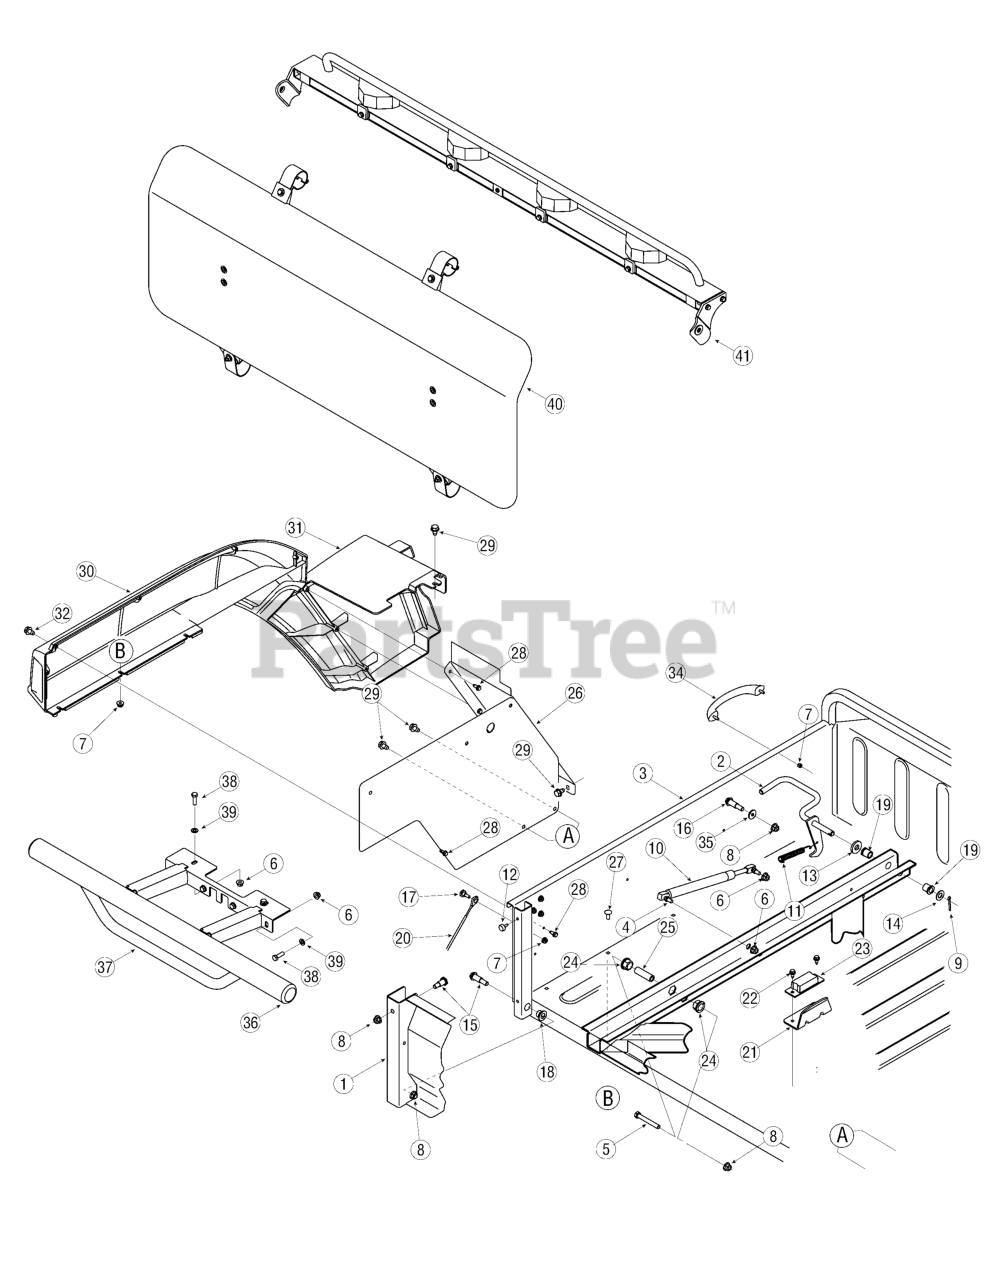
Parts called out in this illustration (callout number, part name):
2	Lvr Asm, bed, latch
4	Stud, ball, 5/16-18
5	Screw, 3/8-16, 2.75, gr5, std
6	Nut, flglk, 5/16-18, grf, nylon
7	Nut, flglk, 1/4-20, grf, nylon
8	Nut, flglk, 3/8-16, grf, nylon
9	Pin, cot, 5/32, 1.25
10	Spr, gas, 6.91 Stroke
11	Spr, extn, .50 Od X 4.35 Lg
12	Bmpr, .62 Dia. x .3
13	Wash, flat, .531 X 1.25 X .181
14	Wash, flat, .510 X 1.00 X .060
15	Scr, shldr, .50 X .685, 3/8-16
16	Scr, shldr, .50x.925, 3/8-16
17	Scr, shldr, .375x.280, 1/4-20
18	Brg, flg, hex, .506 Id X .590 Lg
19	Brg, flg, .503 X .689 X .792
20	Cable, lanyard
22	Scr, tt, 1/4-20x.625, hxindwsh
23	Bmpr, suspn, extn
24	Brg, hex Flng .629 Id
25	Spcr, .390 Id X.625 Od X2.03 Lg
27	Scr, Crg, 1/4-20, .62, Gr2
28	Scr, #12-16, .50, Hxindwsh
29	Scr, Tt, 5/16-18, 0.500
30	Fdr, Lh Rear
30	Fdr, Lh Rr, Camo
31	Fdr, Lwr Lh Rear
31	Fdr, Lwr Lh Rr, Camo
32	Screw, Mach., 1/4-20 x .750
33	Washer, Bell, .340 x .872 x .060
35	Washer, Flat, .385 x .870 x .092
36	End Cap
39	Washer, Flat, .330 x .630 x .0635
40	Head Rest
41	Light Bar
